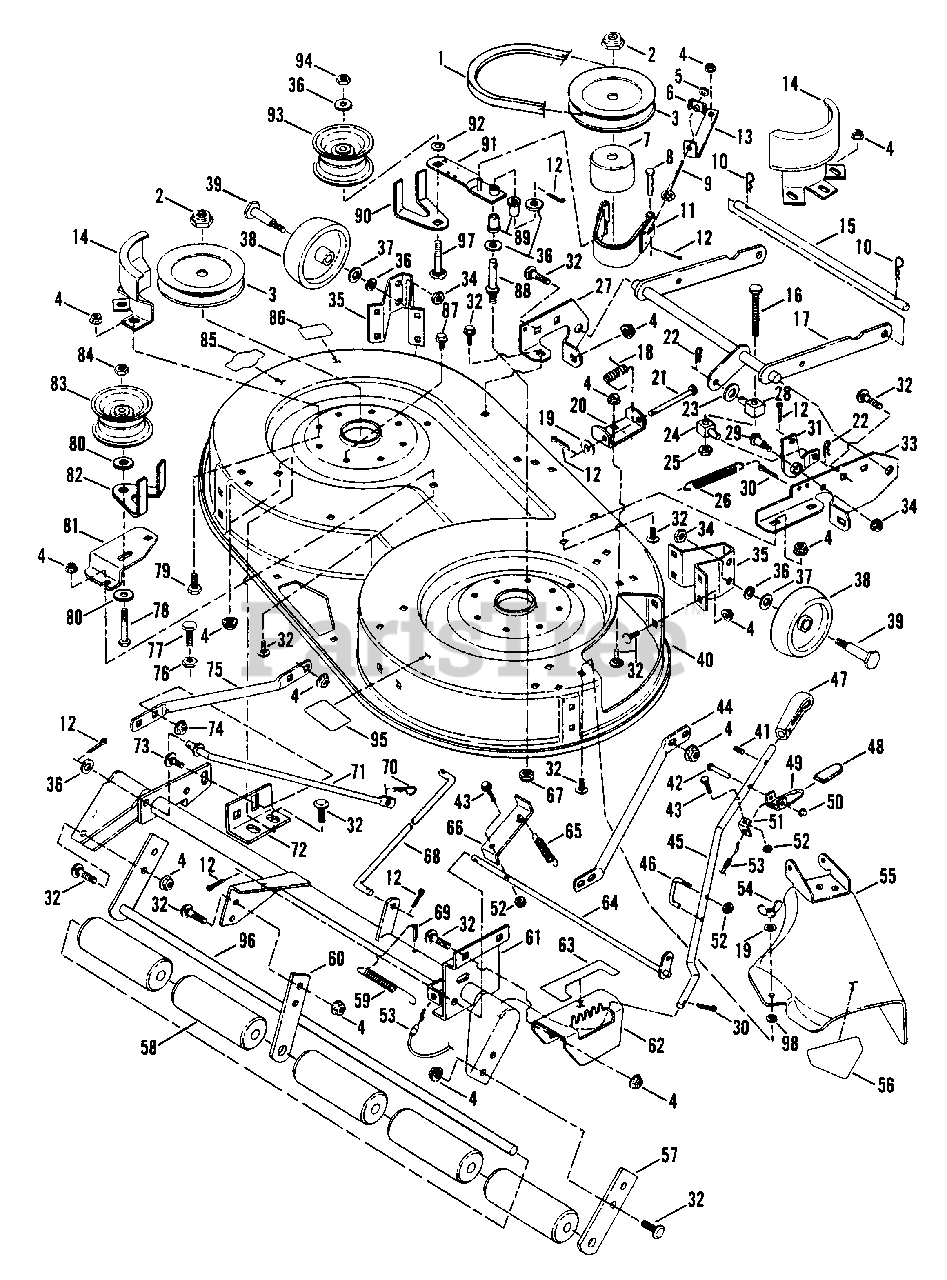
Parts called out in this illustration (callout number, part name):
1	BELT, Drive, 38" Cutting Deck HA 95.5" EL
2	NUT, 5/8-18 Hex Nyloc
3	PULLEY, Spindle
4	NUT, 5/16-18 Hex Flange Lock
5	NUT, 1/4-20 Hex GR 5 YZ
6	NUT, 1/4-20 "T" Lock
7	DRUM, Brake
8	PIN, 1/4 x 1 5/8" Clevis
9	BOLT, 1/4-20 Eye
10	PIN, Hair .148 X 2.62 YZ
11	ASSEMBLY, Brake Band
12	PIN, 3/32 x 3/4" Cotter
13	ANCHOR, Blade Brake
14	GUARD, Belt
15	PIN, Deck Hanger
16	SCREW, 1/2-13 x 3-1/4" Hex Cap
17	LIFT, Front Arm
18	SPRING, Chute Deflector Hinge
19	WASHER, Flat 5/16
20	HINGE, Deck
21	PIN, 5/16 x 3-3/16" Clevis
22	PIN, Hair, 3/32 x 1-19/32"
23	WASHER, Flat .531X1X.063 BZ
24	SWIVEL, Lift
25	NUT, 1/2-13 Hex Jam
26	SPRING, Blade Brake
27	HITCH (Left Hand)
28	SWIVEL, Lift 1/2-13THD
29	BOLT, 3/8-24 x 1.33" Hex Shoulder
30	PIN, 1/8 x 1" Cotter
31	BELLCRANK
32	BOLT, 5/16-18 x 3/4" Carriage
33	BRACKET, Front Linkage
34	NUT, 3/8-24 Hex Center Lock
35	BRACKET, Gage Wheel Front
36	WASHER, 3/8" Flat
37	WASHER, 1/2 Flat
38	WHEEL, Gage 4x1.5
39	BOLT, 3/8-24 Shoulder
40	DECK, 38" Cutting (Drill holes as needed)
41	PIN, 3/16 x 3/4" Roll
42	PIN, 1/4 x 1 1/16" Round Head
43	SCREW, 1/4-20 x 1" Hex Cap (Gr. 5)
44	TUBE, Structural (Right Hand)
45	HANDLE, Lift
46	CATCH, Lift Handle
47	KNOB, Lift Handle
48	GRIP, Lever
49	LEVER, Latch
50	NUT, 1/4" Push
51	ANCHOR, Cable
52	NUT, 1/4-20 Hex Top Lock
53	CABLE, Transport Latch
54	WING-NUT, 5/16-18
55	ASSEMBLY, Chute Deflector
56	DECAL, DANGER
57	STRIP, Outer
58	ROLLER
59	SPRING, Extension
60	STRIP, Center
61	ASSEMBLY, Torque Tube
62	QUADRANT, Height Adjustment (No longer available)
63	DECAL, Height Adjustment
64	ASSEMBLY, Latch Shaft
65	SPRING, Extension
66	CATCH, Up-Latch
67	NUT, 5/16-24 Hex
68	LINK, Deck
69	PIN, 3/16 x 1-3/4" Cotter (No longer available)
70	PIN, 5/64 x 1-3/16" Hair
71	BAR, Stabilizing
72	ANGLE, Adjustment
73	BOLT, Carriage, 3/8-16 X 1
74	NUT, 318-16 Hex Lock
75	TUBE, Structural (Left Hand)
76	NUT, 3/8-16 Hex Jam
77	SCREW, 3/8-16 x 1 1/2" Hex Head Cap, Grade 5
78	SCREW, 1/2-13 x 3 1/2" Hex Head Cap, Grade 5
79	BOLT, 5/16-18 x 1" Hex Head Cap
80	WASHER, 13/32 x 1.50 O.D. Flat
81	BRACKET, Idler
82	GUIDE, Belt
83	PULLEY, Idler 3.25 OD x 1.75 Flat
84	NUT, 1/2-13 Hex (Nyloc)
85	DECAL, 38" Deck
86	DECAL, CAUTION (Rotating Blades)
87	SCREW, 3/8-16 x 3/4" Self-Tapping
88	STUD, Idler
89	BUSHING, Flange
90	GUIDE, Belt
91	ARM, Idler Pulley
92	RETAINER, 3/8 Bolt
93	PULLEY, Idler 3.25 OD x 1.75 Flat
94	NUT, 3/8-16 Hex Nyloc
95	DECAL - CAUTION
96	ASSEMBLY, Roller Shaft
97	BOLT, 3/8-16 x 2-3/4" Carriage (Gr. 5)
98	RETAINER, 5/16 Bolt
